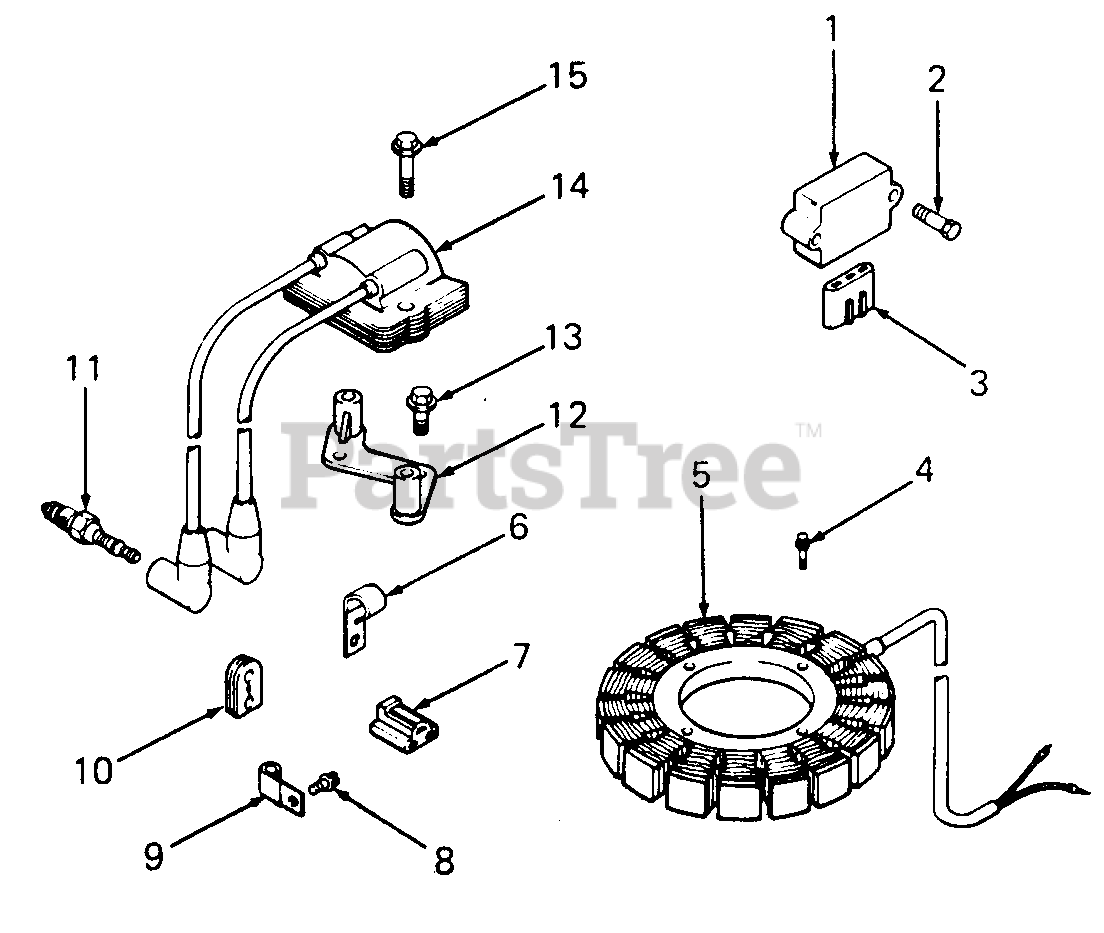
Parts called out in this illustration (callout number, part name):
1	Rectifier, Regulator
2	Screw, H.C. Sems, 1/4-20 X 5/8
3	Connector, Female (3 contact)
4	Screw, Hex Wash Hd, 10-24 X 3/4
5	Stator Kit, 15 amp
6	Clip, Cable
7	Connector, Male (3 contact)
8	Screw, Hex Wash Hd, 1/4-20 X 7/16
11	Spark Plug
12	Bracket, Module
13	Screw, Hex Wash Hd, 1/4-20 X 7/8
14	Module, Ignition w/ Diode
15	Screw, Hex Wash Hd, 1/4-20 X 1
